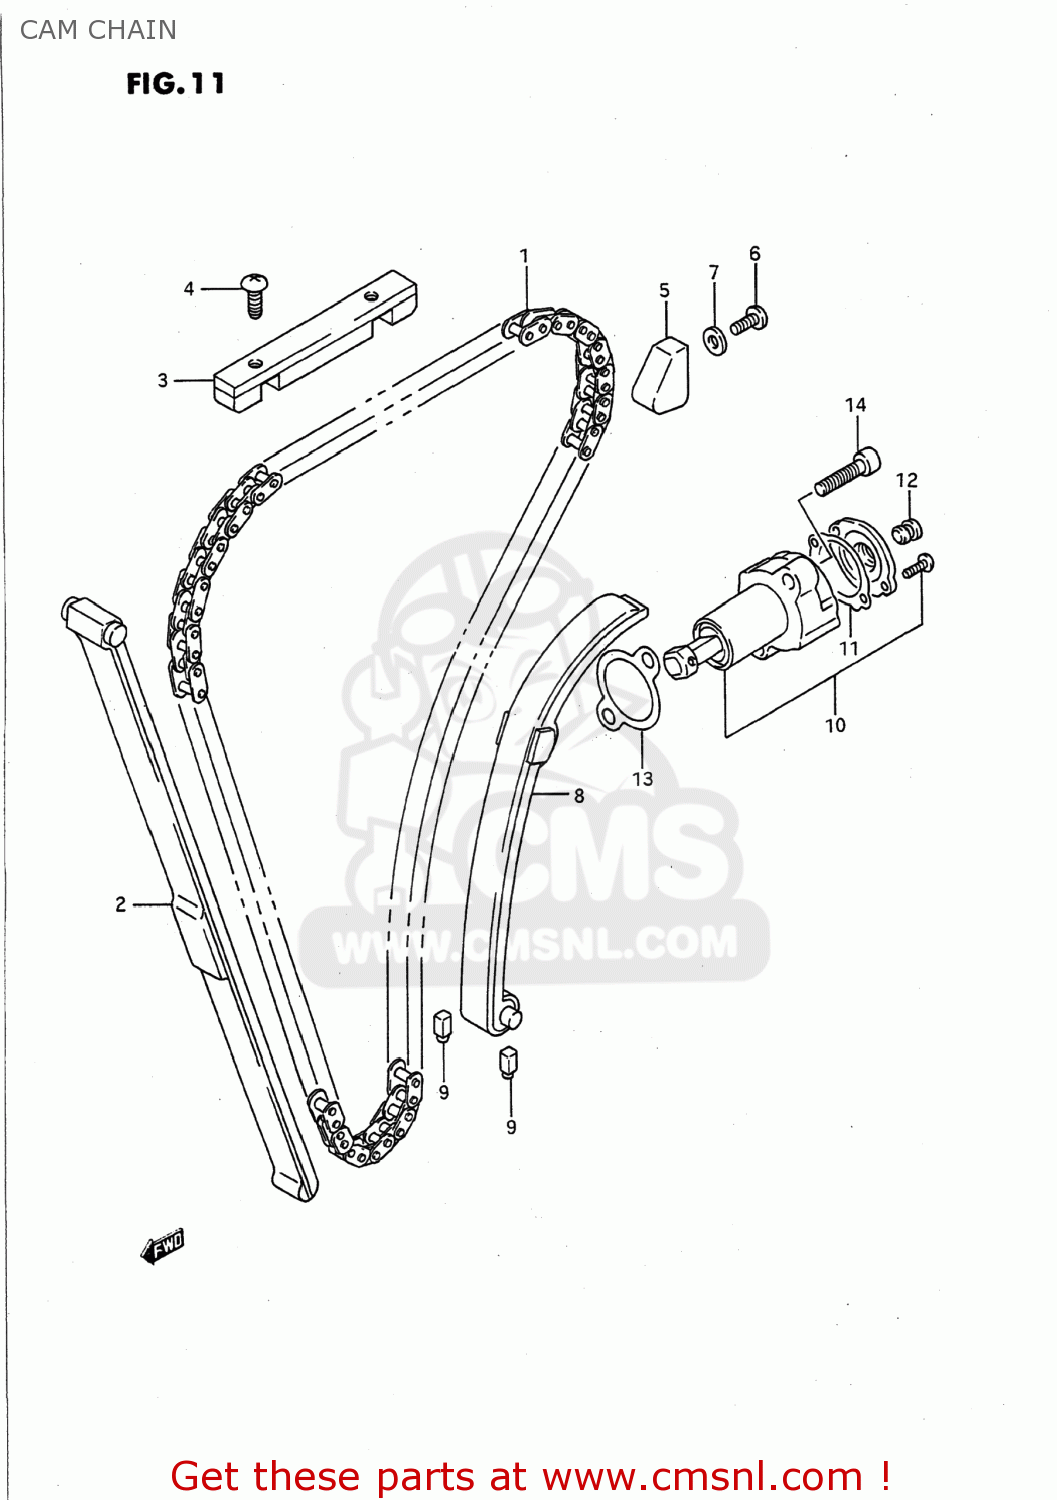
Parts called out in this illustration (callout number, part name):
1	CHAIN,CAMSHAFT DRIVE(120L)
2	GUIDE,CAM CHAIN NO.1
3	GUIDE,CAM CHAIN
4	SCREW
5	GUIDE,CAM CHAIN
6	BOLT
7	GASKET(5.8X13X1.2) (NAS)
8	TENSIONER,CAM CHAIN
9	CUSHION,CAM CHAIN TENSIONER
10	ADJUSTER ASSEMBLY,TENSIONER
11	GASKET,ADJUSTER CAP (MCA)
12	PLUG,ADJUSTER
13	GASKET,TENSIONER ADJUSTER (NAS)
14	BOLT
